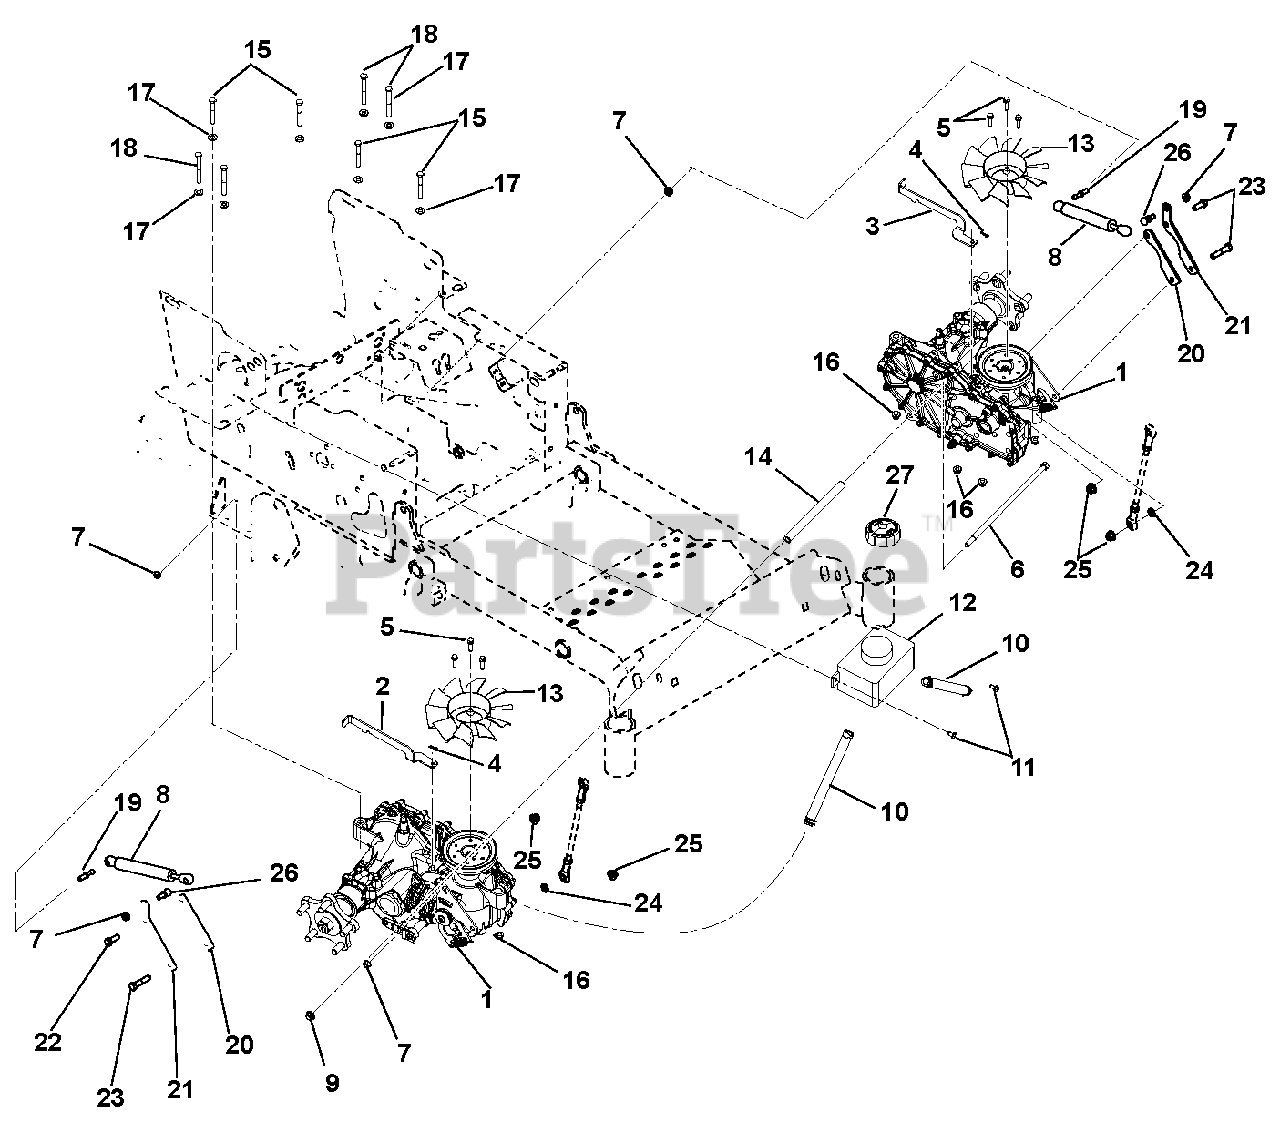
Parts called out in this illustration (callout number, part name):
1	Transaxle, 3100 Series – Left Hand (page 16)
1	Transaxle, 3100 Series – Right Hand (page 18)
2	Right Hand Dump Valve Lever – Black
3	Left Hand Dump Valve Lever – Black
4	Pin, Hair, Internal .06 x .18 x .77
5	Screw, Tapping .25-20 x 1.00 Hex Washer Head Thread
6	Bolt, Hex .38-16 x 11.00 Grade 5
7	Nut, Top Lock Flange
8	Damper, Stabilus
9	Nut, .38-16 Nyloc Flange
10	Assembly, Hydro Overflow Tank Hose
11	Screw, Tapping .25-20 x .50 Hex Washer Head Thread
12	Tank, Expansion
13	Fan, Cooling
14	Spacer, .38 ID x 5/8 OD x 7.72
15	Bolt, Hex .31-18 x 2.50 Grade 5
16	Nut, Nyloc Flange .312-18
17	Washer, Flat Steel .344 x .688 x .065
18	Bolt, Hex .31-18 x 3.00 Grade 5
19	Ball Stud, Threaded
20	Plate, Reinforcement
21	Plate, Damper Mounting
22	Bolt, Hex .38-16 x 1.00 Grade 5
23	Bolt, Hex 3/8-16 x 1.75 Grade 5
24	Washer, Locking .38 x .094
25	Nut, Nyloc Flange 3/8-16
26	Ball Stud, Threaded
27	Cap, Hydro Reservoir Replacement
